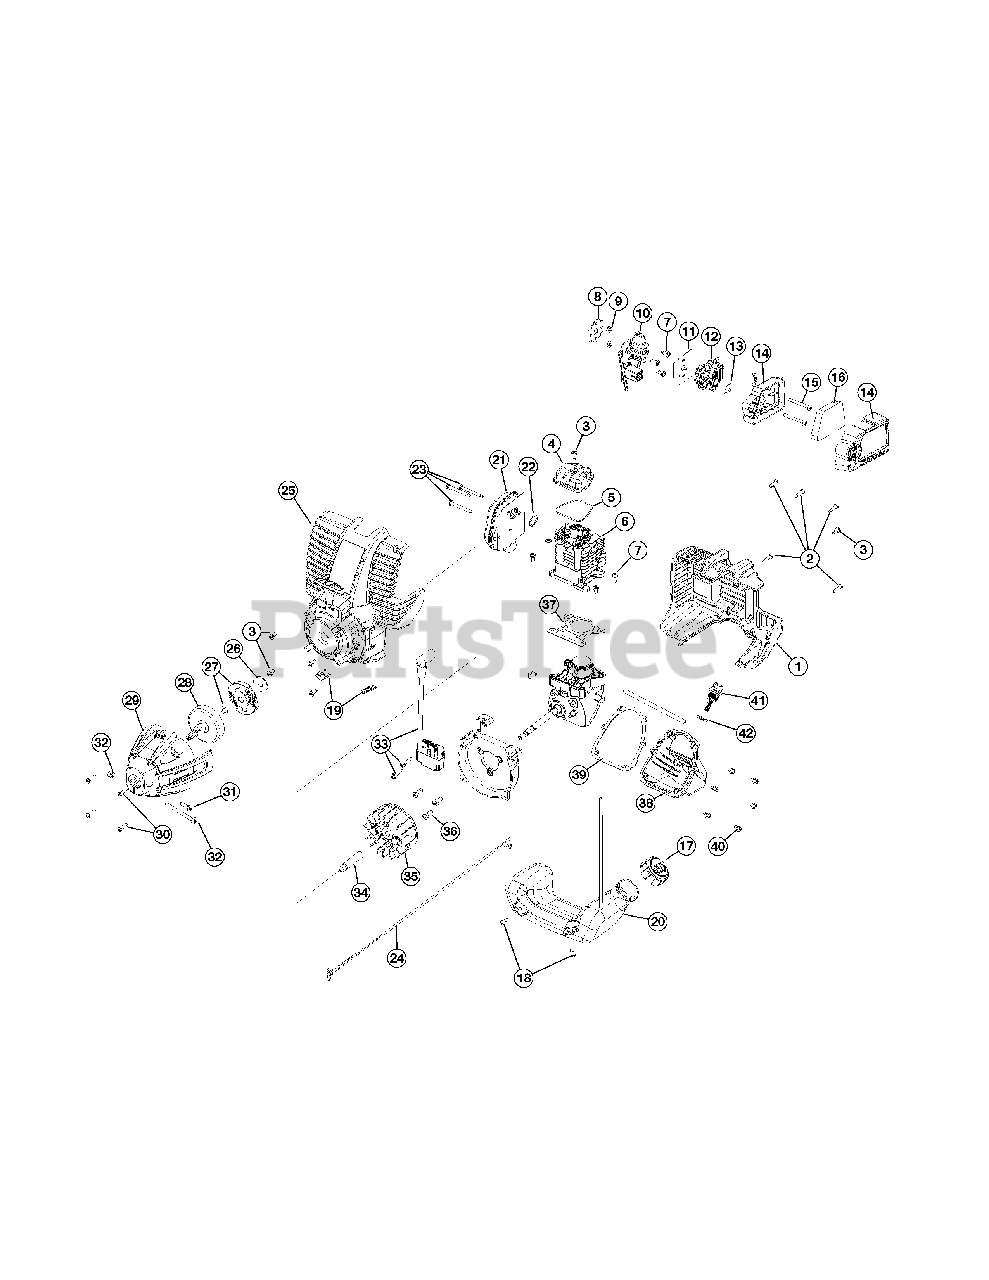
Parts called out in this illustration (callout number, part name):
1	Engine Cover
4	Valve Cover
5	Valve Cover Gasket
6	Cylinder Assembly
7	Cylinder Screw
8	Insulator Gasket
10	Insulator
11	Carburetor Gasket
12	Carburetor w/Primer
13	Carburetor O-Ring
14	Air Filter Cover Assembly
15	Air Filter Mounting Screw
16	Air Filter
20	Fuel Tank Assembly
21	Muffler Assembly
22	Muffler Gasket
23	Muffler Mounting Screw
25	Starter Housing Assembly
27	Clutch Assembly
28	Clutch Drum
29	Clutch Cover Assembly
30	Cover Screw
31	Anti-Rotation Screw
32	Clamping Screw Assembly
33	Ignition Module Assembly
36	Shroud Screw
37	Cylinder Gasket
38	Oil Pan
39	Oil Pan Gasket
40	Oil Pan Screw
41	Dipstick Assembly
43	Rope Guide w/Cap
